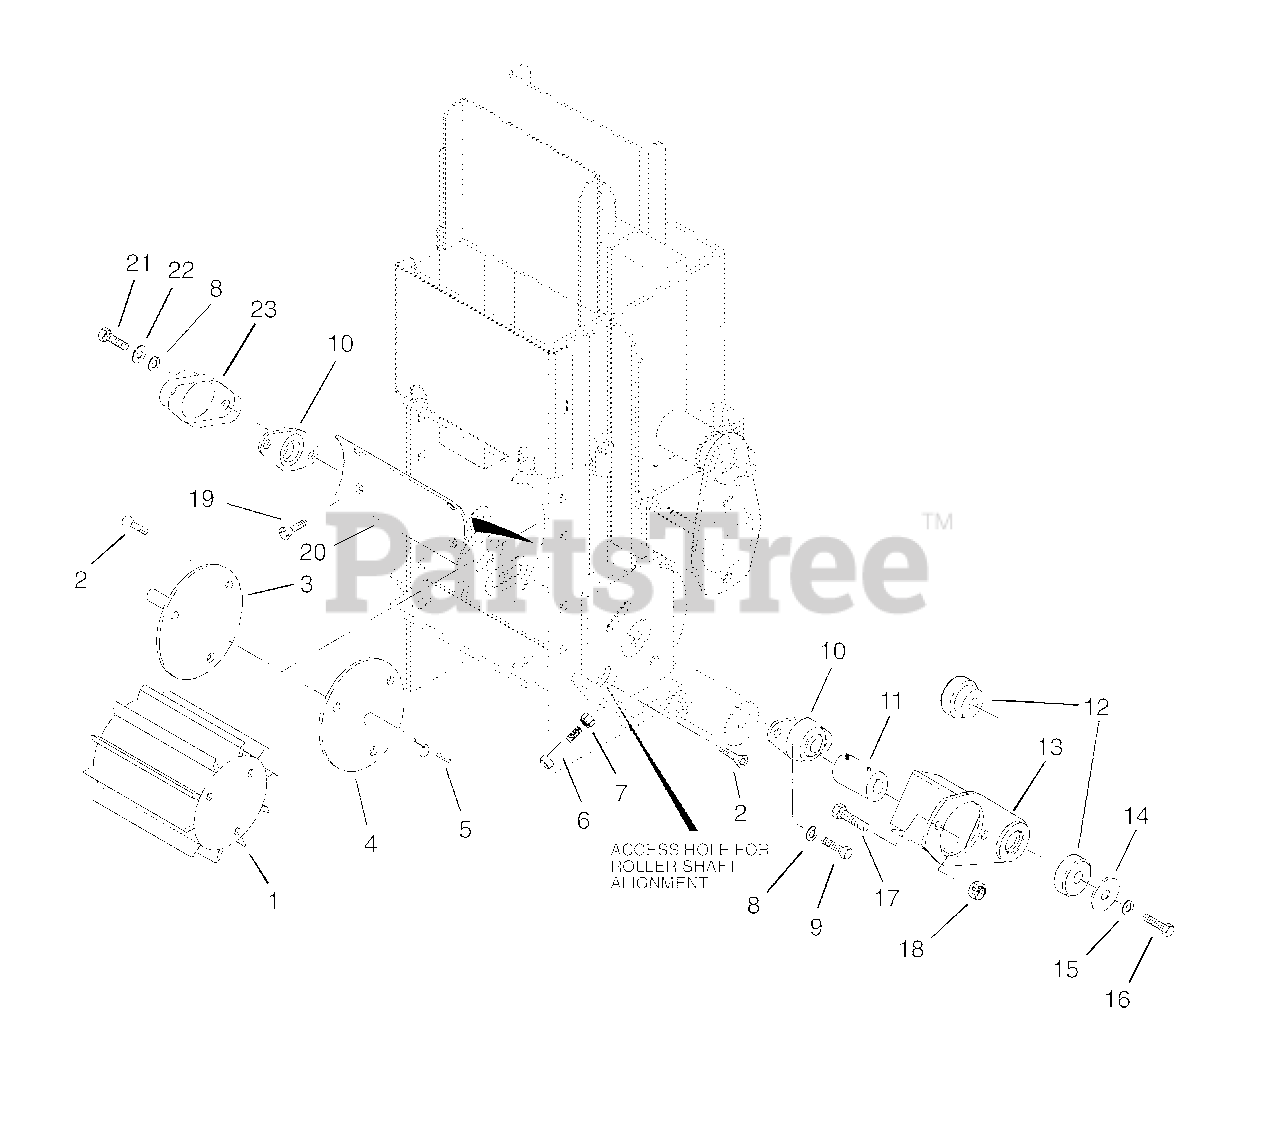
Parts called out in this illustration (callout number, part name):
2	Bolt-Flat Socket Head .50-13 x 1.0
3	Roller Shaft - Left
4	Roller Shaft - Right
5	Key-Square
6	Bolt-Hex-Full Thread .38-13 x 3.50
7	Nut-Hex .38-16
8	Washer-Locking .44 x .109
9	Bolt-Hex .44-14 x 1.25 Grade 5
10	Bearing Flange
12	Rubber Bushings
13	Torque Arm Weldment
14	Washer-Flat-Steel .50 x 2.25 x .13
15	Washer-Locking .50 x .125
16	Bolt-Hex .50-13 x 3.00 Grade 5
17	Bolt-Hex .50-13 x 1.50 Grade 5
18	Nut-Locking-Center .50-13
19	Screw-Machine .25-20 x .50 FLTCNTRSK
20	Wrapper-Inner
21	Bolt-Hex .44-14 x 1.50 Grade 5
22	Washer-Flat-Steel .505 x 1.00 x .062
23	Cover-Bearing Feed Roll
